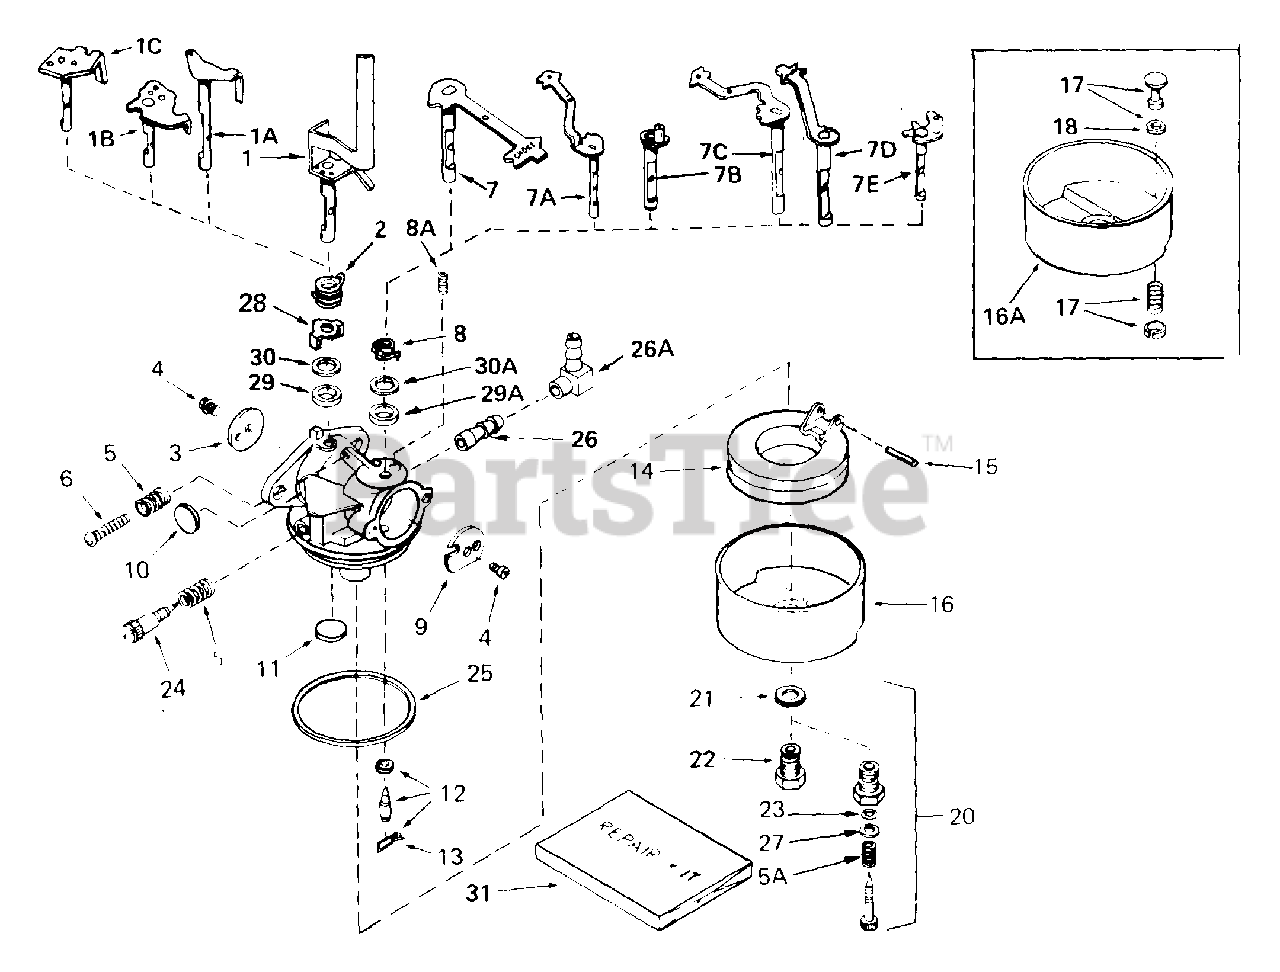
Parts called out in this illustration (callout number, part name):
1A	"Shaft & Lever Assy., Throttle
2	Spring, Throttle return
3	Shutter, Throttle
4	Screw, Throttle & Choke shutter
5	Spring, Regulating screw
5A	Spring, Main adj. screw
6	Screw, Idle regulating
7A	Shaft & Lever Assy., Choke
8A	Spring, Choke positioning
9	Shutter, Choke
10	Plug, Welch
11	Plug, Welch
12	Inlet Needle, Seat & Clip Assy.
13	Clip, Inlet needle
14	Float, Carburetor
15	Shaft, Float
16	Bowl, Float
20	Adjustment Screw Assy., Main
21	Gasket, Bowl-to-body
23	"O" Ring, Adjustment screw
24	Screw, Idle adjustment
25	Gasket, Bowl-to-body
31	Repair Kit
